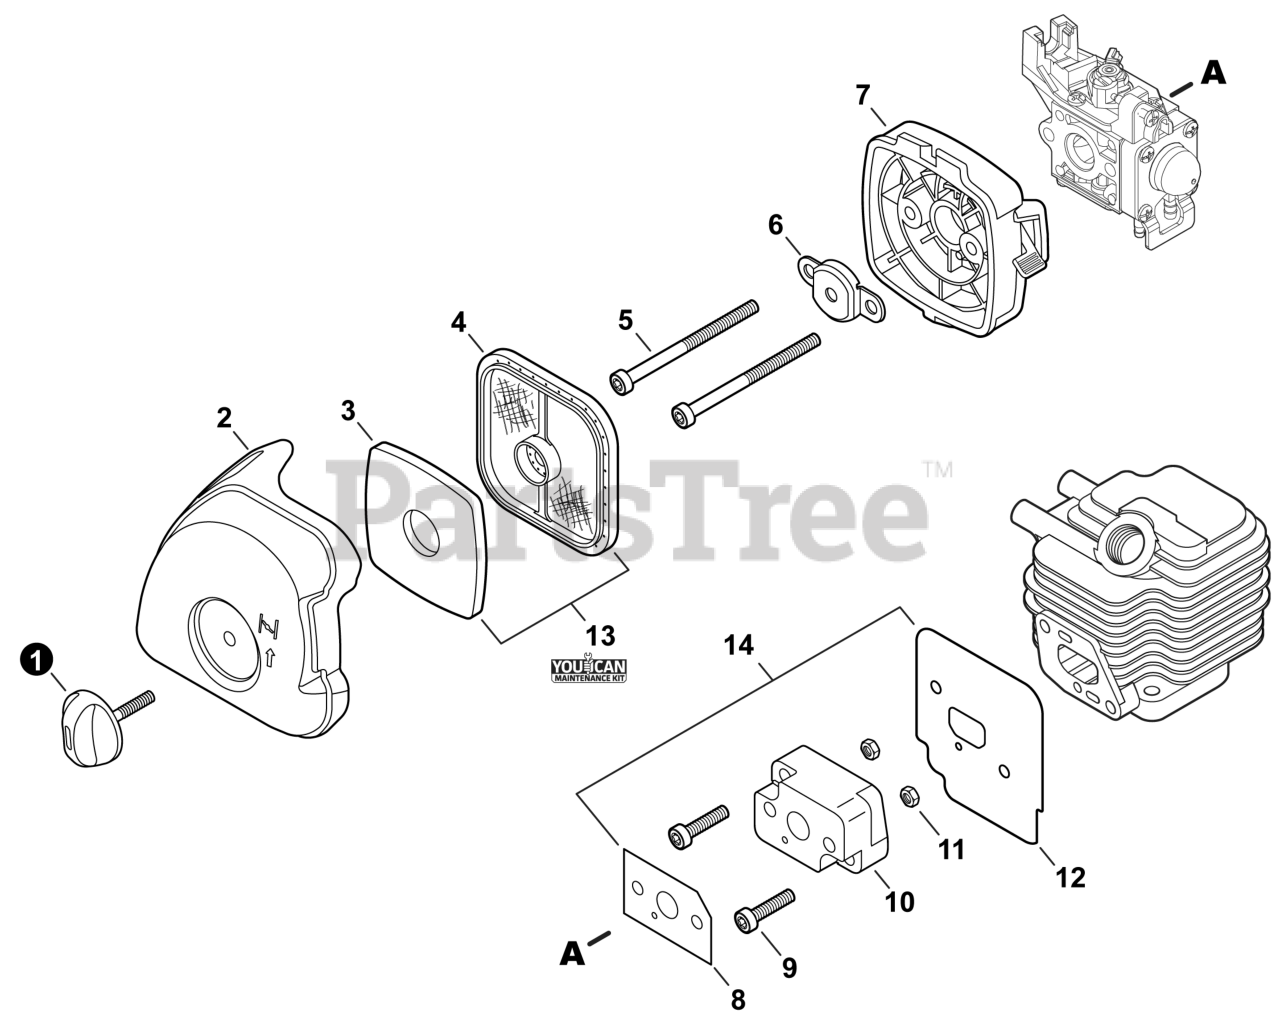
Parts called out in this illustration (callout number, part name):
1	THUMBSCREW
2	COVER, AIR FILTER
3	PRE-FILTER, FOAM
4	FILTER, AIR - DOUBLE LAYER
5	BOLT, TORX 5x65
6	PLATE, PREVENT
7	CASE, AIR FILTER
8	GASKET, INTAKE
9	BOLT, TORX 5x20
10	INSULATOR, INTAKE
12	HEAT SHIELD, INTAKE
13	TUNE-UP KIT - YOUCANT
14	GASKET KIT: ENGINE, INTAKE, EXHAUST
